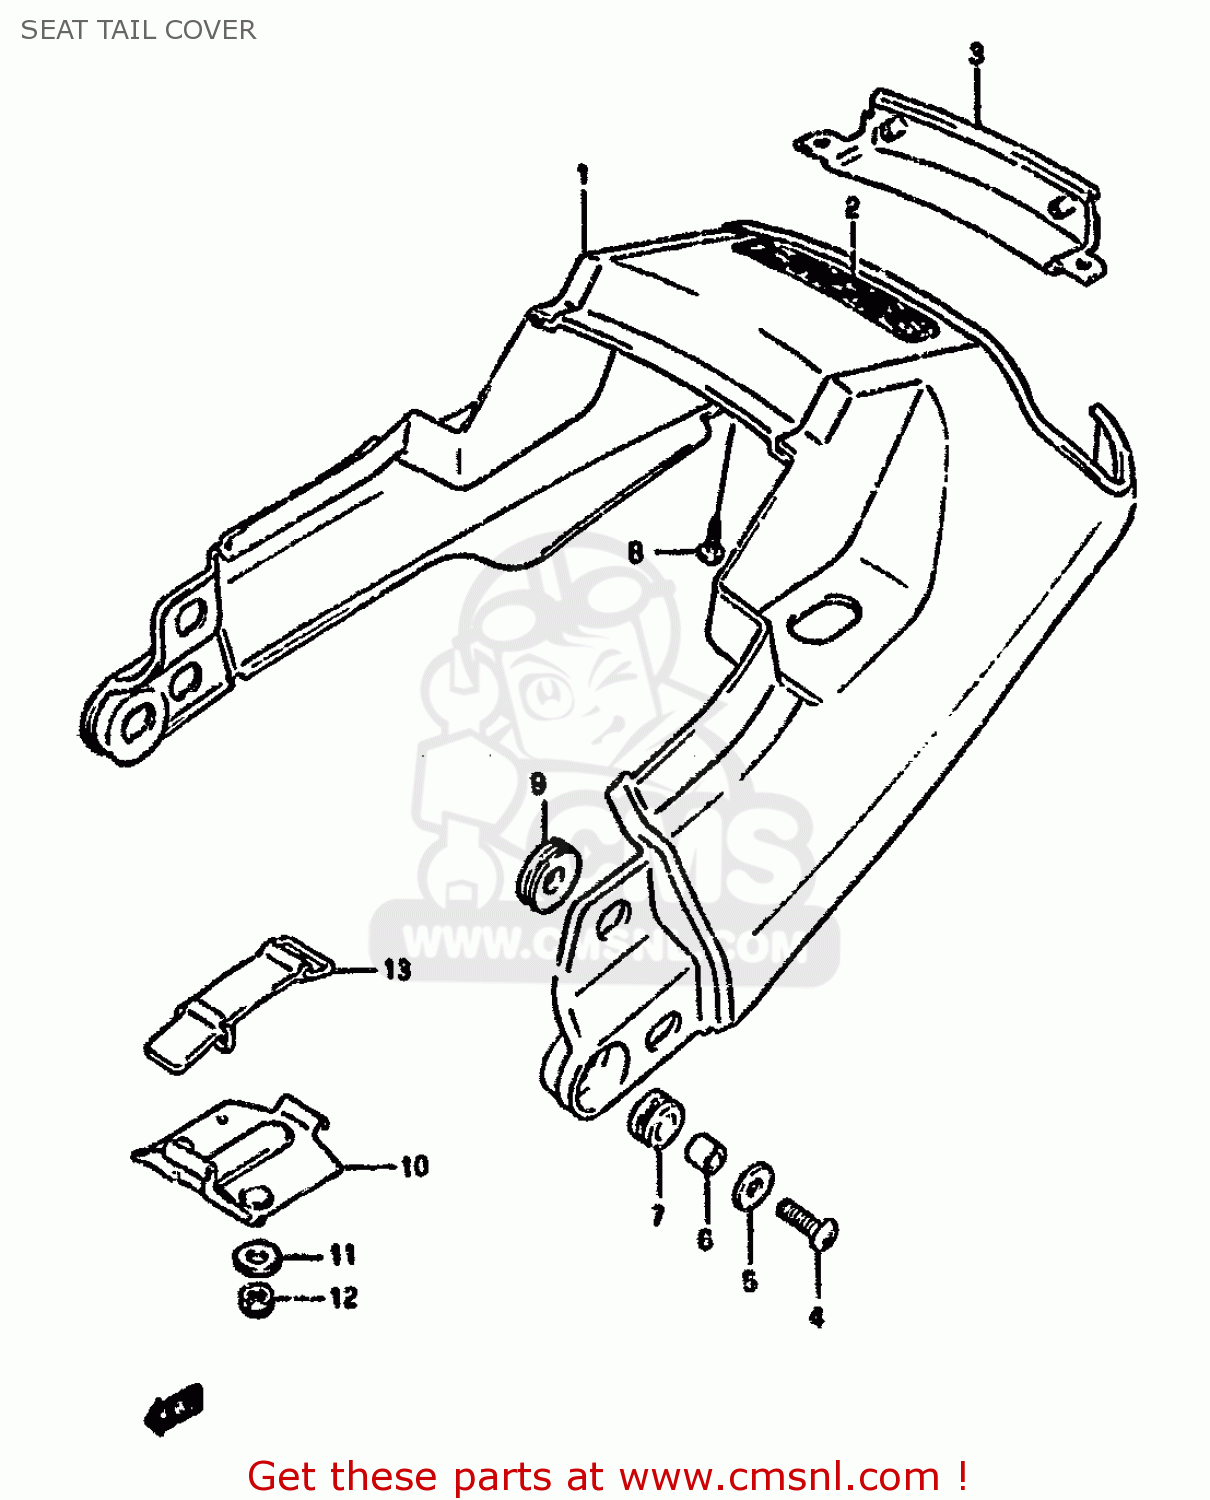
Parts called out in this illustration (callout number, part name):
1	COVER ASSEMBLY,SEAT TAIL
2	EMBLEM,SEAT TAIL COVER
3	COVER,SEAT TAIL,LOWER
4	SCREW
5	WASHER(6.5X18X1)
6	SPACER
7	CUSHION
8	SCREW
9	CUSHION
10	HOLDER,TOOL
11	WASHER
12	NUT
13	BAND
